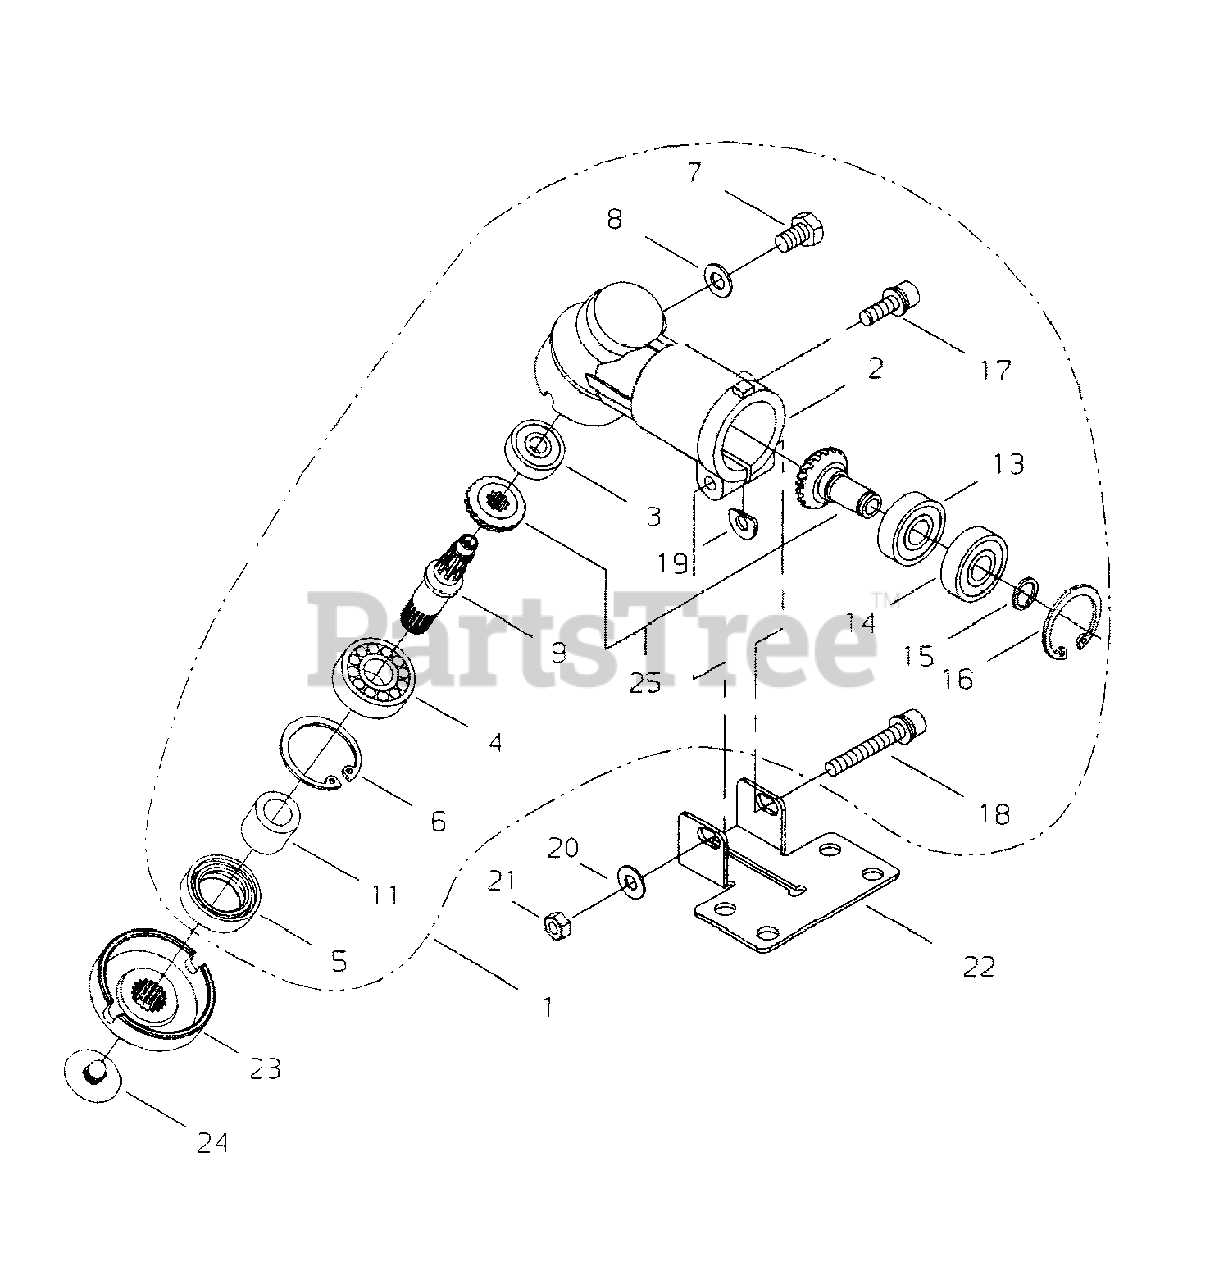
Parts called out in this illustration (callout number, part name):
1	GEAR CASE ASSY
2	HOUSING, GEAR CASE
3	BEARING, BALL 608 DDU
4	BEARING, BALL 6001
5	SEAL, OIL
6	RING, SNAP Ø28
7	BOLT M6×10
8	WASHER 6.5×11.5×0.8
9	SHAFT, GEAR
11	SPACER
13	BEARING, BALL 609
14	BEARING, BALL 609ZZ
15	RING, SNAP Ø9
16	RING, SNAP Ø24
17	BOLT M5×16
18	BOLT M5×35
19	D-WASHER
20	WASHER 5.5×12×0.8
21	NUT M5
22	PLATE, SHIELD MOUNTING
23	PLATE, ADAPTOR - UPPER
24	PLATE, ADAPTOR - LOWER
25	GUARD, BOLT
26	BOLT 8
27	CLIP, BLADE
28	GEAR SET
